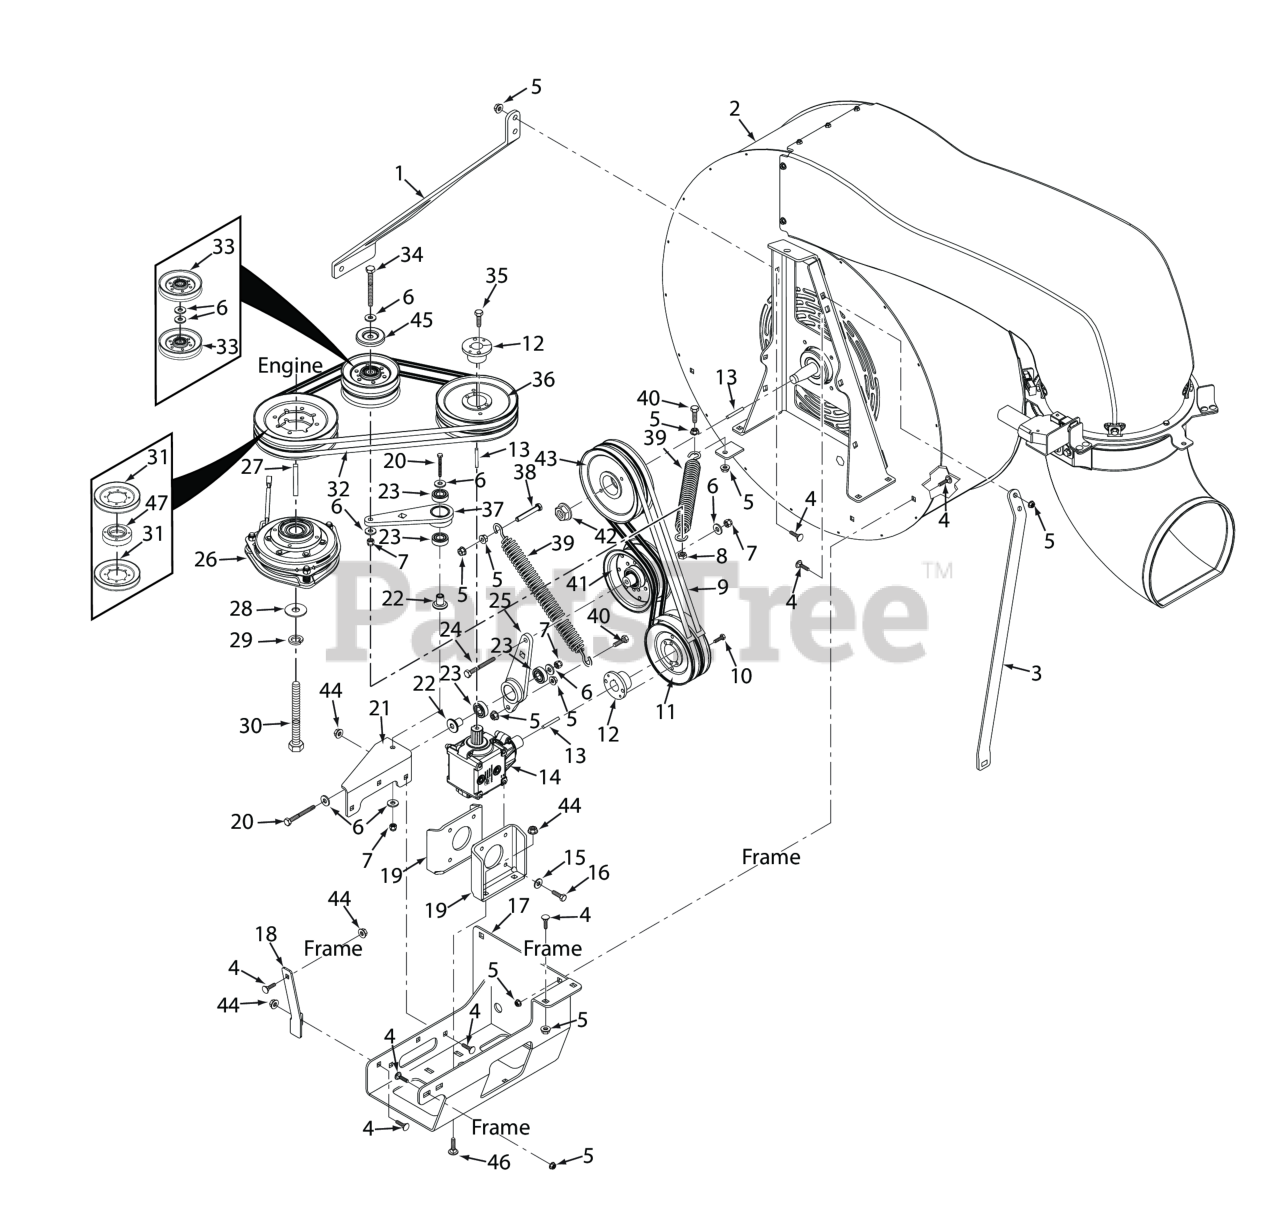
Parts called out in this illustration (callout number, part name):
1	LH Support Bar, Blower
2	Blower Housing, With Decal
3	RH Support Bar, Blower
4	Carriage Bolt, 3/8-16 x 1.0"
5	NUT, 3/8-16 SERRATED FLANGE HEX HEAD
6	Flatwasher, 3/8 (.391 x .938 x .105 HD) Grade 8
7	HEX NUT, ELASTIC STOP LOCK, 3/8-16
8	Bolt, Hex Head 3/8-16 x 1" Ser. Flg.
9	C-Belt, Gear Drive Assembly
10	Hub, Tapered, 1" Bore
11	Pulley, Double Groove
12	TAPERED HUB, 1.00" BORE
13	Key, 1/4 x 1/4 x 1.25" Pulley Mtg.
14	Gearbox Assembly
15	Lockwasher, 5/16 (.317 x .586 x .078) Helical Spring
16	Bolt, Heax Head 5/16-18 x 1" (48V / 52V)
17	Mounting Bracket, Gearbox
18	Support Strap, Gearbox
19	Mounting Plate, Gearbox
20	Bolt, Hex Head 3/8-16 x 2-1/4" - 61"
21	Idler Arm Bracket, Gearbox
22	Pivot, Idler Short
23	BEARINGS, BALL, NEUTRAL RETURN
24	Bolt, Hex Head 3/8-16 x 3" - 52"
25	Idler Arm Assembly, Gearbox Output (INCL. 23)
26	Clutch, GT3.5 (28.6mm Bore)
27	Key, 1/4 x 1/4 x 3-1/2"
28	Flatwasher, 7/16-.469 x 1.75 x .25 (48, 52)
29	Lockwasher, 7/16� Spring
30	Bolt, Hex Head 7/16-20 x 3" w/t Patch
31	Pulley, Clutch 7.30 DIA
32	Belt, Gearbox Input
33	IDLER PULLEY, "V" GROOVE
34	Capscrew, Hex Head 3/8-16 x 3-3/4"
35	Bolt, Hex Head 1/4-20 x 1" Grade 8 Black
36	Pulley, Gearbox Input, 6.95 DIA, Double Groove
37	Idler Arm Assembly, Gearbox Input (INCL. 23)
38	Bolt, Hex Head 3/8-16 x 2-1/2" Grade 8
39	Spring, Transmission Drive
40	Bolt, Hex Head 3/8-16 x 1-1/2" Grade 8 Black
41	Pulley, Idler 5" Dia.
42	Nut, 3/4-16 Spriral Lock
43	Pulley, Blower, 6.95 DIA, Double Groove
44	Nut, Flange Elastic Stop Nut, 3/8-16
45	Quick Pin, 5/16" Dia.
46	Bolt, Carriage 3/8-16 x 1"
47	Hub, Clutch Pulley
